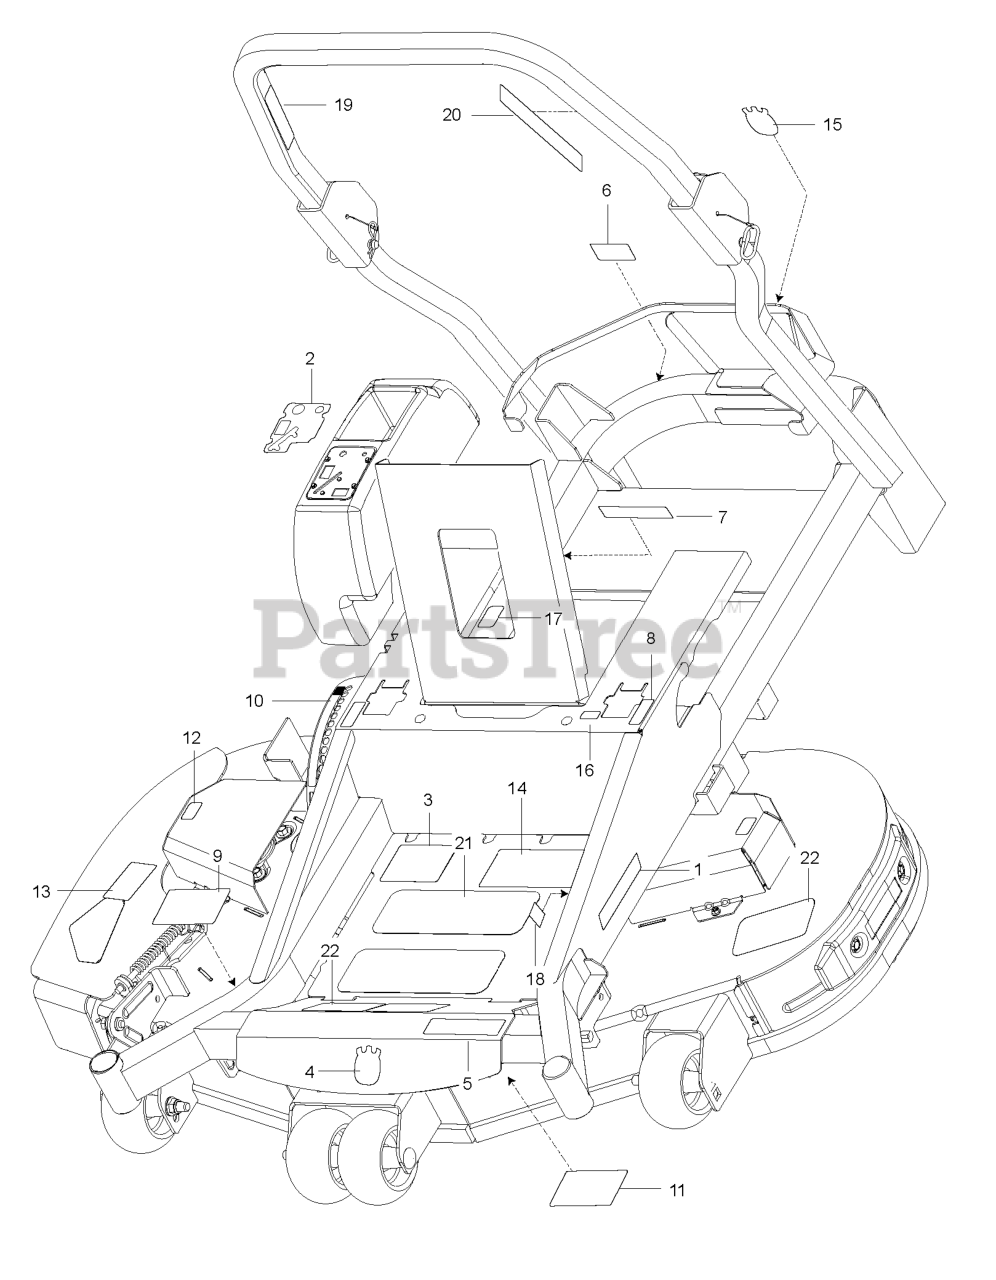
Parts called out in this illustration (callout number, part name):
1	RP.DECAL.BADGE.170MM.TEXTLOGO
2	DECAL, CONSOLE HUS
3	DECAL.ZTR.STRTNGINST.REMOTECHK
4	DECAL.AUGER.HUSQ.CROWN.SNOW
5	DECAL.MZ52
6	DECAL, BELT DRIVE
7	EURO DECAL-BATTERY WARNIN6
8	DECAL.ZTR.MOTCONTRL.SYMBOL.HUS
9	DECAL, BELT ROUTING
10	DECAL, HEIGHT ADJUST
11	DECAL, SERVICE
12	DECAL.DECK.6MIL.EURO.NOSTEP
13	DECAL.DECK.6MIL./DEF.SHLD.WARN
14	DECAL.ZTR.WARNING.SMARTIGNITIN
15	DECAL, CROWN H, 110MM
16	DECAL.STR.S.T.SYSMBOLONLY.2014
17	DECAL CERTIFICATION DECAL EMCC
18	DECAL.80.DBA.AUSTRALIA
19	DECAL, ROPS, WARNING
20	DECAL ROPS
21	DECAL, DECK DEFLECTOR, WARNING
22	ANTI-SKID PAD
